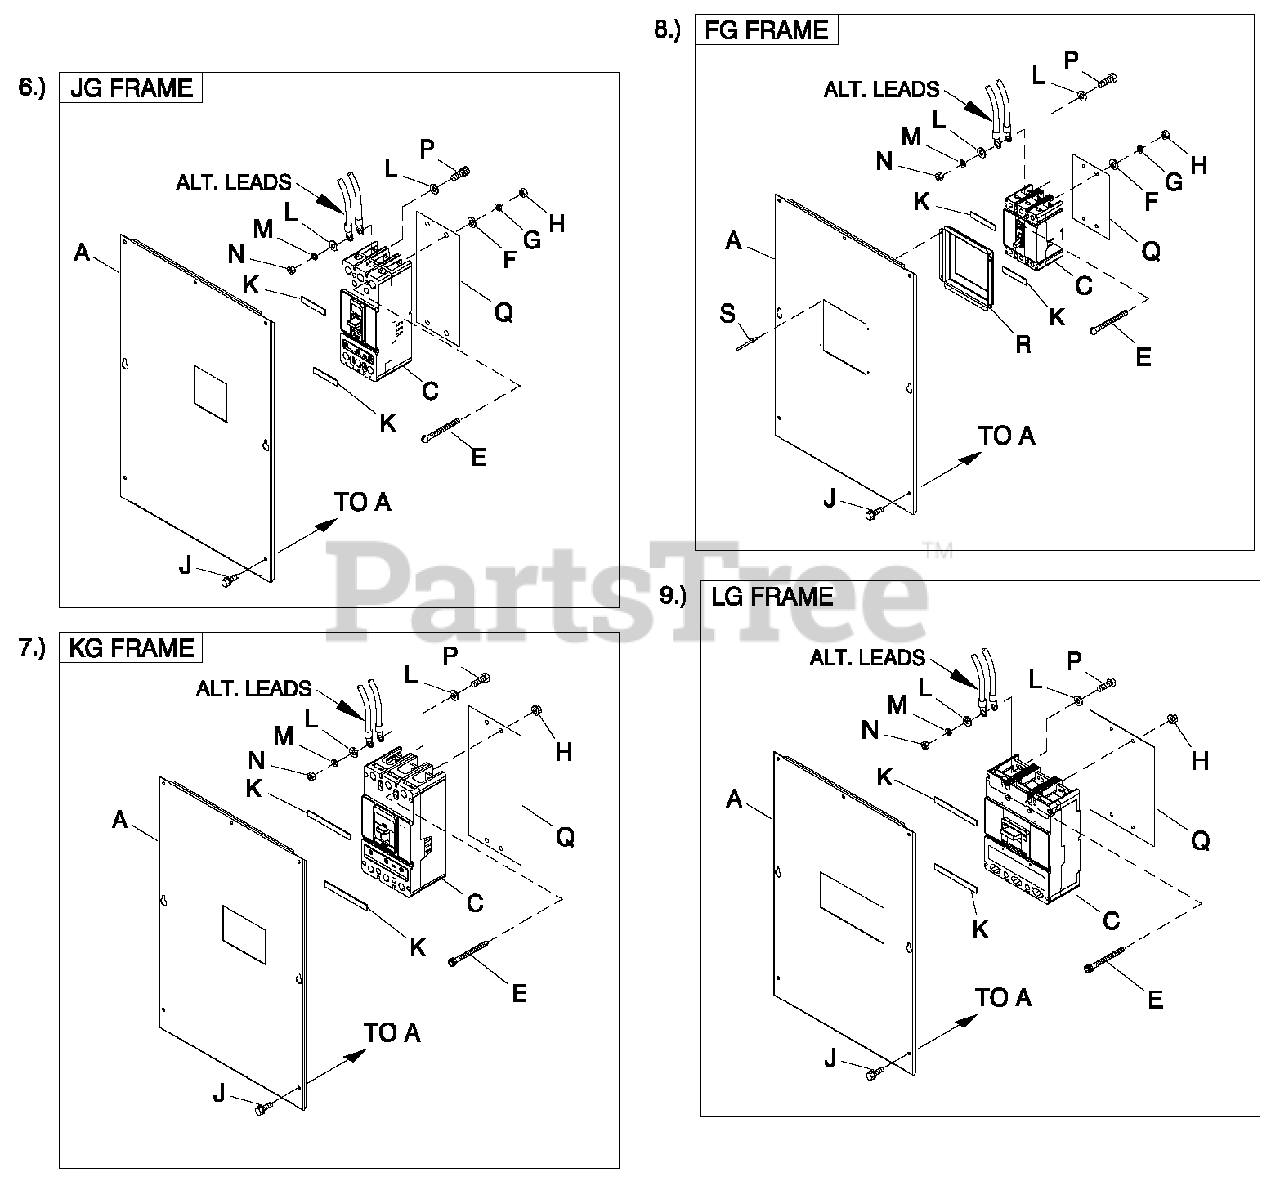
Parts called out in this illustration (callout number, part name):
6	UL CIRCUIT BREAKER (JC)
7	UL CIRCUIT BREAKER (KG
9	UL CIRCUIT BREAKER (LG
A	COVER CB E JG FRAME C5
C	CB 0250 3P 600V E JG LL
E	SCREW RHM 1 /4-20X 3
F	WASHER FLAT 1/4-M6 ZINC
G	WASHER LOCK M6-1/4
H	NUT HEX 1/4-20 STEEL
J	SCREW THF M6-1 X 16 N WA Z/JS
K	TAPE ELEC 1/2 FOAM
L	WASHER FLAT 5/16-M8 ZINC
M	WASHER LOCK M8-5/16
N	NUT HEX M8-1.25 G8 CLEARZINC
P	SCREW HHC M8-1.25 X 25 C8.8
Q	INSULATOR CB E 3P JG
A	COVER CB E KG FRAME C5
C	CB 0350 3P 600V E KG LL
E	SCREW SHC M6-1.0 X 50 C8.8
H	NUT FLANGE M6-1.0 NYLOK
Q	INSULATOR CB E 3P KG
A	COVER CB G 225AF C5
C	CB 0150 3P 480V E FG LL
E	SCREW PPHM #8-32 X 1-3/4 ZINC
F	WASHER FLAT #8 ZINC
G	WASHER LOCK #8-M4
H	NUT HEX #8-32 STEEL
L	WASHER FLAT #10 ZINC
M	WASHER LOCK M5
N	NUT HEX M5-0.8 G8 CLEAR ZINC
P	SCREW HHC M5-0.8X 20 G8.8
Q	INSULATOR CB 3P E TYPE CC/FG
R	COVER CB DISH 3P E FD
S	RIVET POP .125 X .275 SS
A	COVER CB E LG FRAME C5
C	CB 0450A 3P 600V E LG LL
Q	INSULATOR CB E 3P LG
